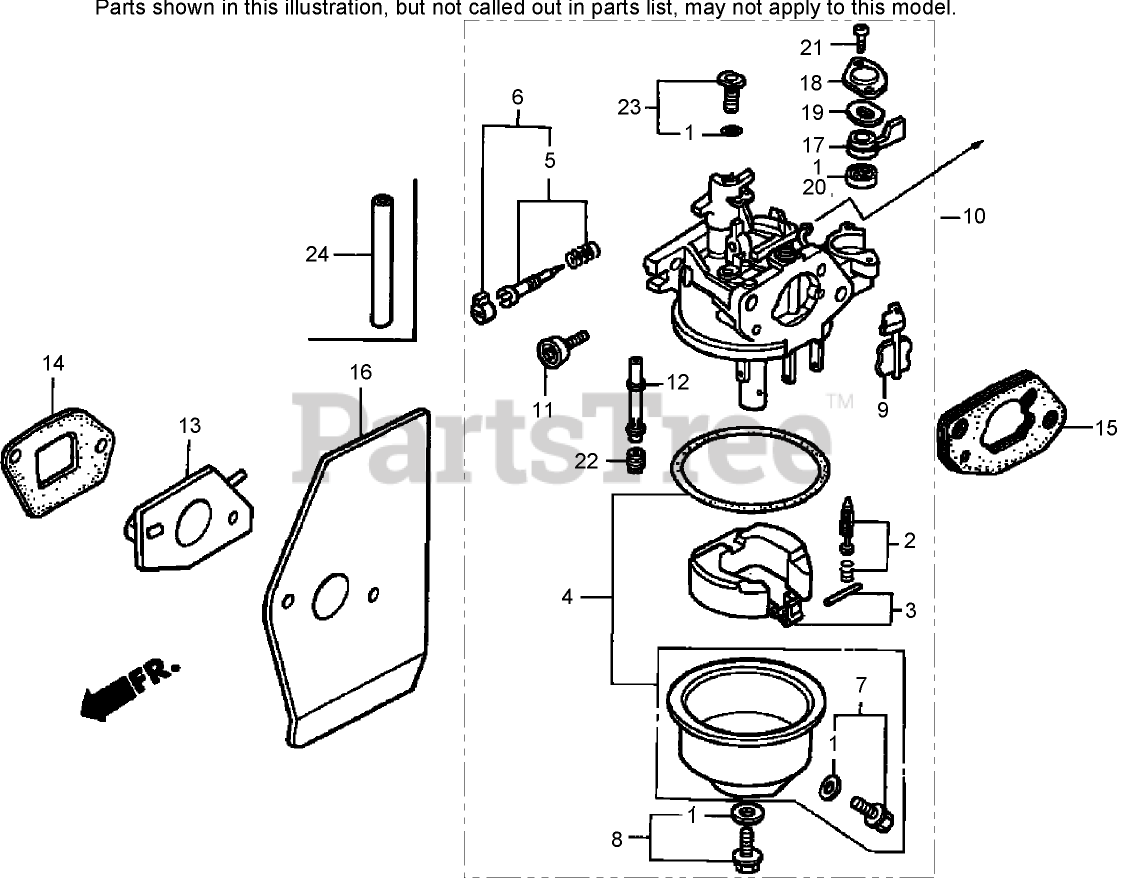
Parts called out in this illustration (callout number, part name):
1	GASKET SET
2	FLOAT VALVE SET
3	Float Set
4	FLOAT CHAMBER SET
6	PILOT SCREW SET
7	DRAIN SCREW SET
8	SCREW SET
9	Choke Set
10	CARBURETOR ASM
11	SCREW- STOP, THROTTLE
12	Nozzle-Main
13	Insulator-Carburetor
14	Gasket-Insulator
15	Spacer-Carburetor
16	Gasket-Carburetor
17	LEVER-VALVE
17	LEVER-PETCOCK
18	PLATE-SETTING, LEVER
19	SPRING-LEVER, PETCOCK
20	GASKET-PETCOCK
21	SCREW-PAN (3X6)
21	SCREW-PAN (3X8)
22	JET-MAIN (No. 60)
22	JET-MAIN (No. 62)
22	JET-MAIN (No. 65)
23	PILOT JET SET (No. 35)
